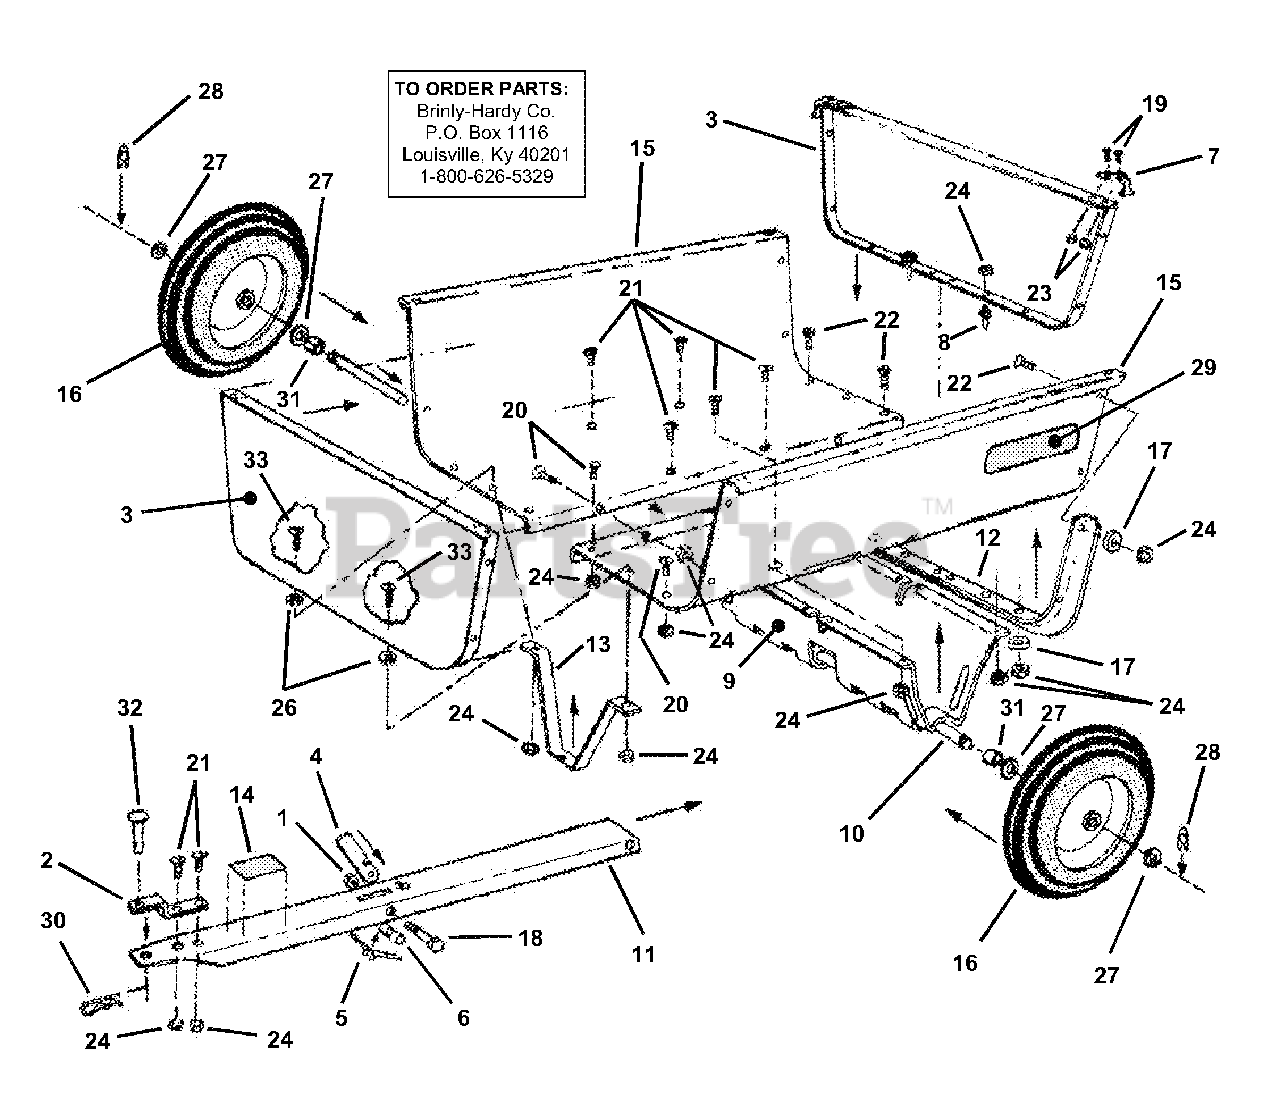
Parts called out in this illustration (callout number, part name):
1	NUT, 3/8 Hex Lock
3	END PANEL, F/R
4	BAR, Handle Lock
5	SPRING, Handle
6	SPACER, Handle
7	BRACKET, Gate Lock
8	PIN, Gate Retainer
9	SUPPORT, Axle
12	ANGLE, Support
13	BRACKET, Lock
14	DECAL, Caution
15	BED HALF, R/L
17	WASHER, Special
18	BOLT, 3/8 x 3-1/2" Hex Hd.
19	SCR., 1/4 x 1/2" Round Hd.
20	SCREW, 5/16 x 1/2" Round Head
21	SCREW, 5/16 x 3/4" Truss Head
22	SCR., 5/16 x 3/4" Flat Hd.
23	NUT, 1/4 Hex Lock
24	NUT, 5/16 Hex Lock
26	WASHER, 5/16 Lock
27	WASHER, 3/4" Flat
28	"E" RING, 3/4"
29	DECAL, Logo
30	HAIRPIN, 1/8"
31	SPACER, Short
32	PIN, 1/2 x 2-1/4" Drawbar
33	SCREW, 5/16 x 1" Round Head
